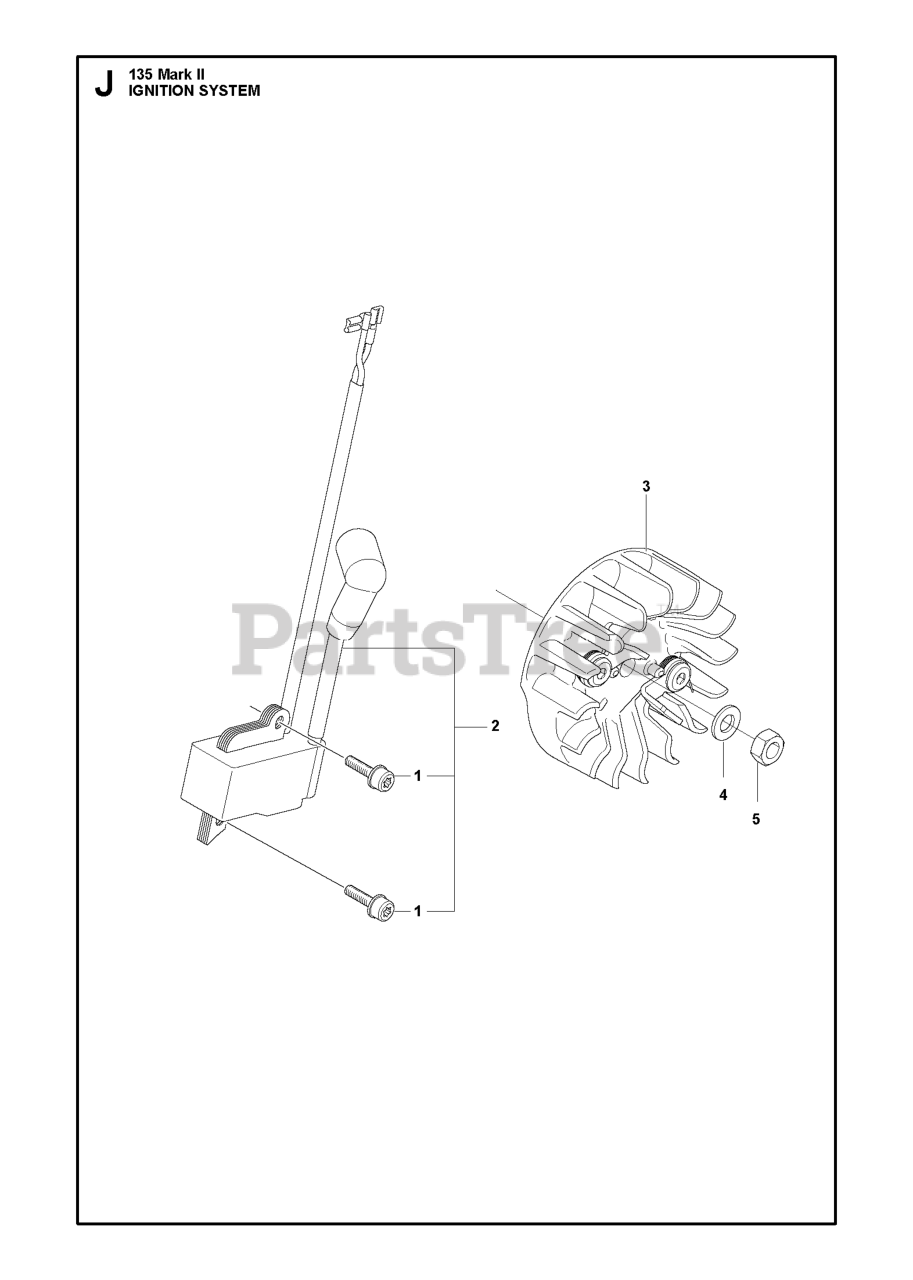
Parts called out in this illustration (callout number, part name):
1	SCREW M4 0.7 X 16MM
2	SERVICE KIT IGNITION MODULE
3	FLYWHEEL ASSY
4	WASHER-FLYWHEEL
5	NUT-FLYWHEEL
